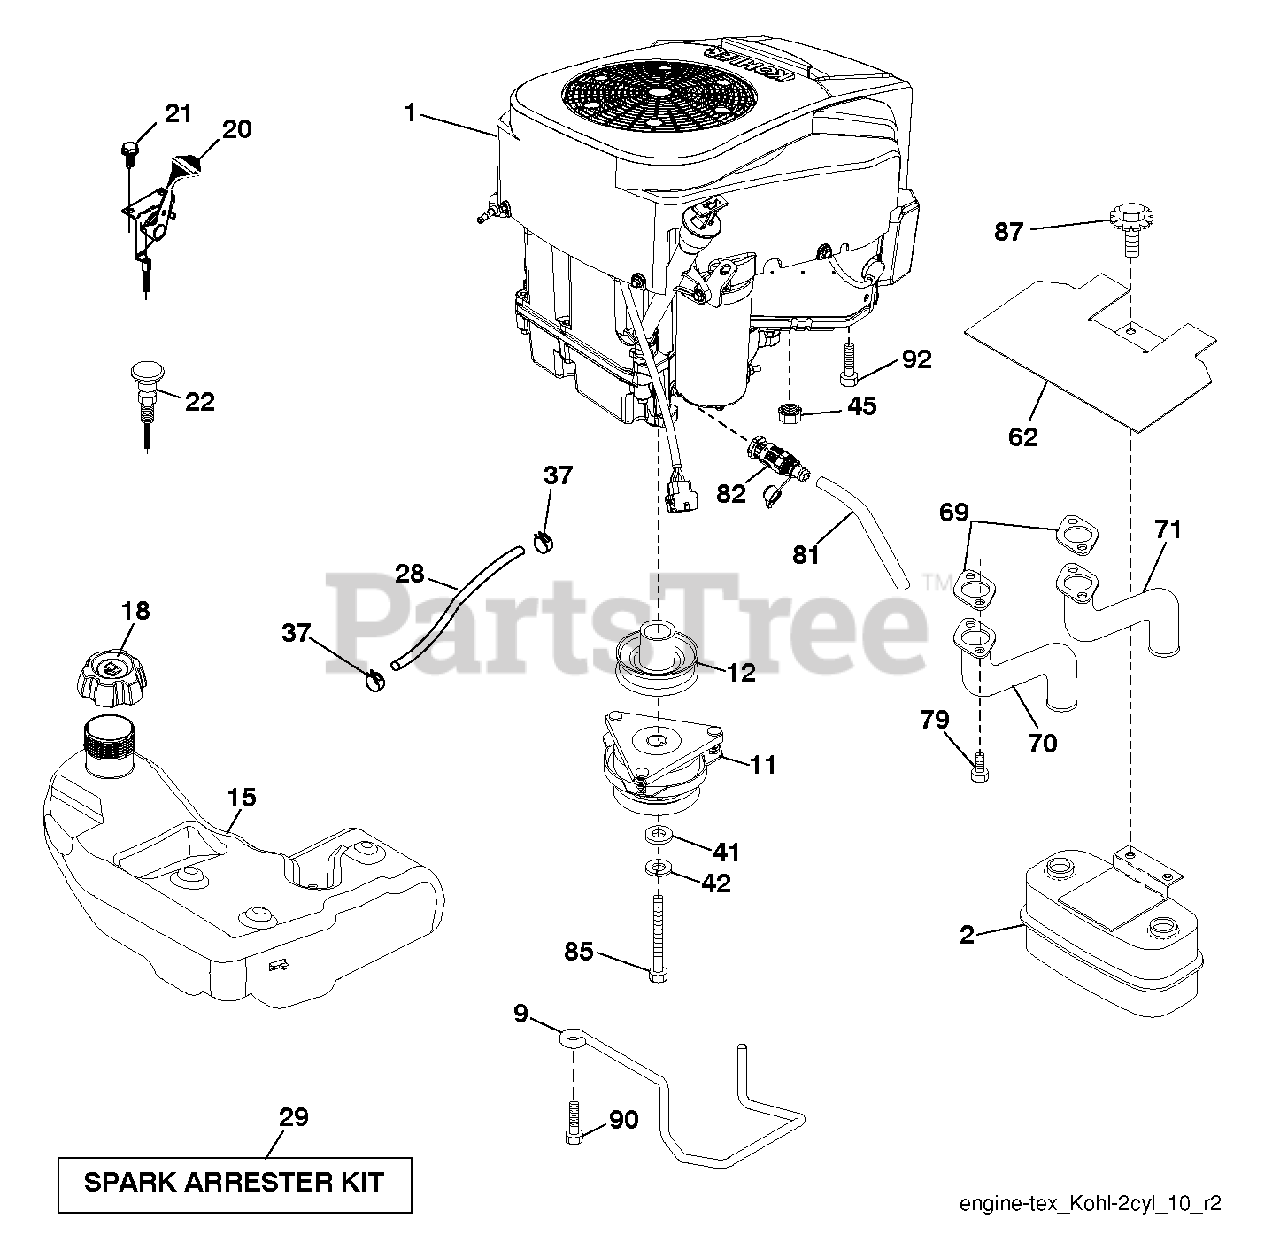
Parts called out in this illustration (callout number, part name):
2	MUFFLER.TWIN.CYL.LOW.TONE
9	Belt Keeper, 4 25"2 Blt 431
11	CLUTCH ELECTRIC
12	PULLEY ENGINE
15	TANK.ASM.4.GAL.EPA
18	Fuel Cap Assembly, 3" Black
20	THROTTLE CONTROL
21	SCREW.#10 X 0.750.BOS THREAD
22	CONTROL CHOKE
28	LINE.FUEL.64"REAR.EMIS
29	ARRESTER SPARK (OPTIONAL)
37	HOSE CLAMP
42	LOCKWASHER
45	NUT
62	SHIELD.HEAT.MUFFLER
69	GASKET.EXHAUST.KOHL.CV18-CV26
70	Exhaust Pipe, LH CV18/20
71	Exhaust Pipe, RH CV18/20
79	SCREW.SOCKET HD.5/16-1
81	TUBE, DRAIN OIL ASM.
82	VALUE.OIL.DRAIN
85	BOLT HEX 7/16-20 X 3.75 GR. 5
87	BOLT 5/1618UNC X 3/4 W/ SEMS
90	SCREW 3/8-16X1
92	SCREW 3/8-16X1
